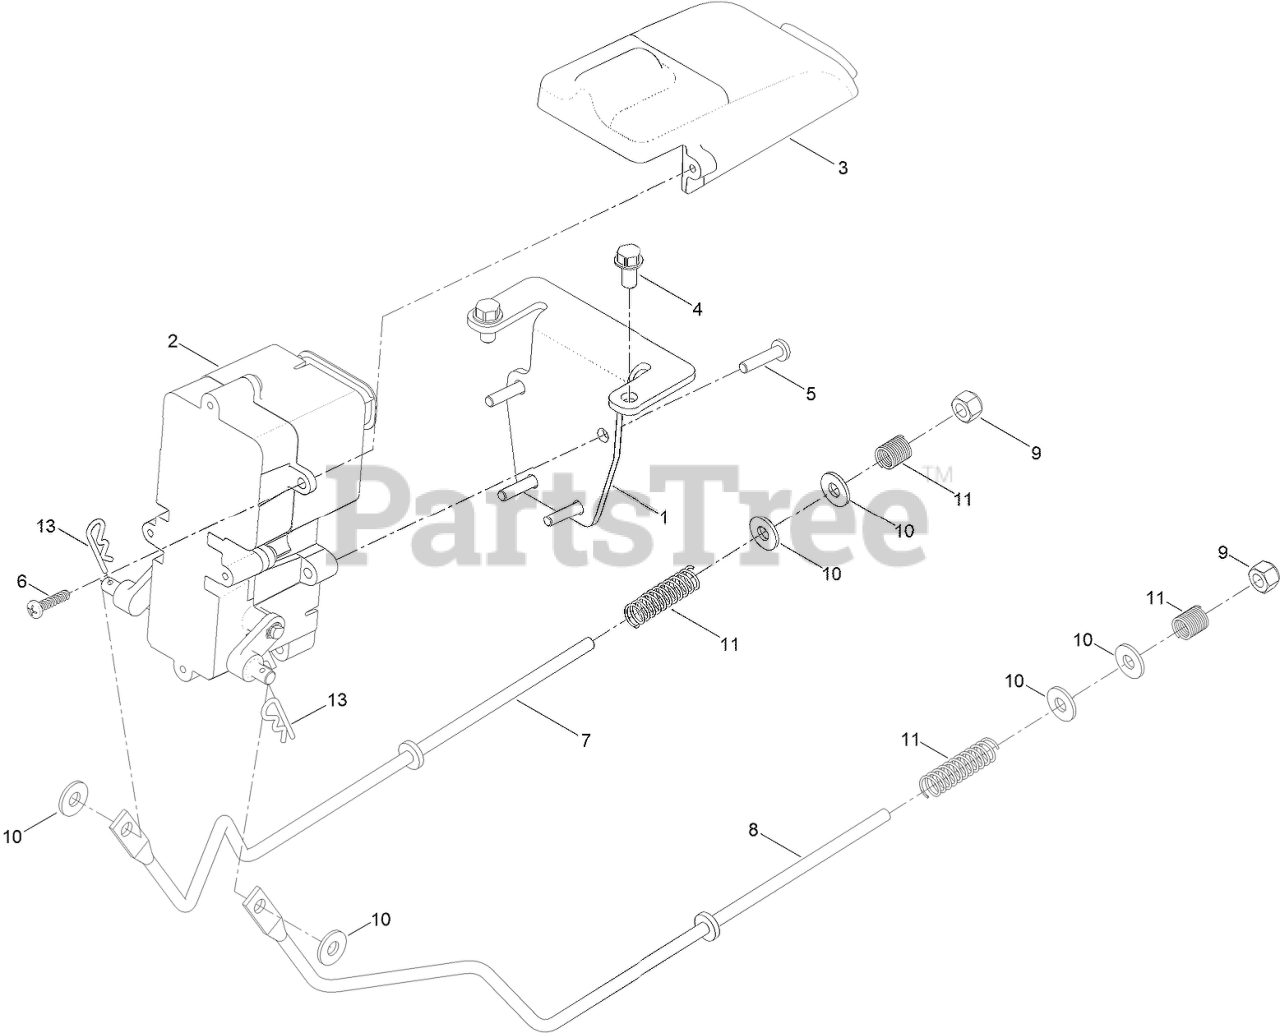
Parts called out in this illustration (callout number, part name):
1	BRACKET-MOUNT, BRAKE
2	BRAKE BOX ASM
3	COVER-CONNECTOR
4	SCREW-HWH
5	SCREW-PPH
6	SCREW-PPH
7	ROD-BRAKE, RH
8	ROD-BRAKE, LH
9	NUT-LOCK, NI
10	WASHER
11	SPRING-COMPRESSION
13	PIN-COTTER
